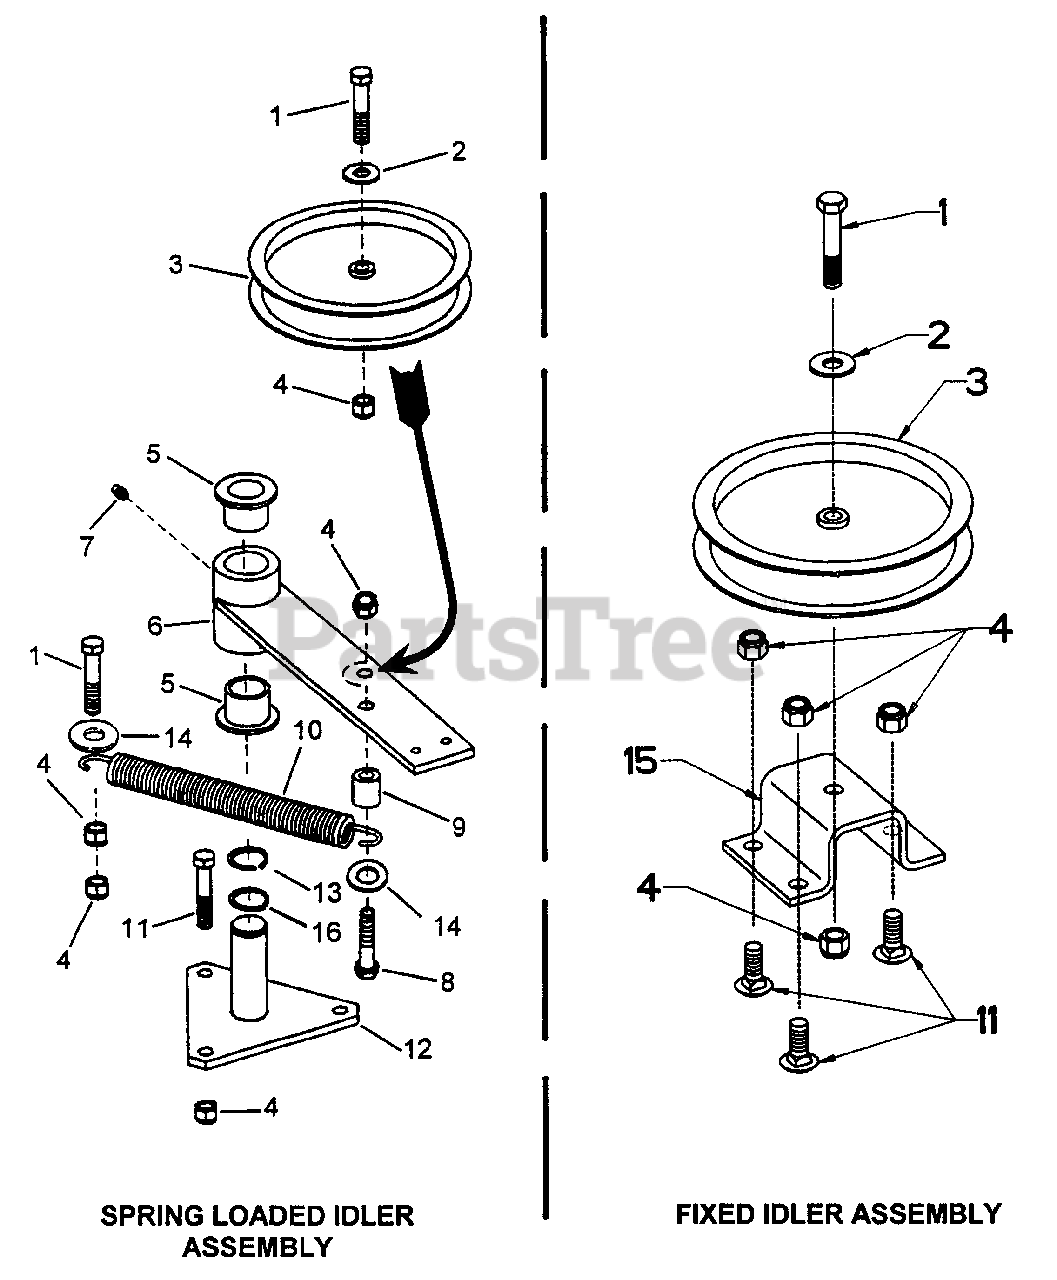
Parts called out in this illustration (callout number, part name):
1	BOLT, 3/8-16 X 2, GD5, CZ
2	WASHER, 3/8" USS
3	PULLEY, Idler 5-1/2" O.D.
4	NUT, 3/8-16 HEX NYLON LOCK
5	BUSHING
6	ARM, Idler (Weldment)
7	FITTING, Lube 1/4-28 Straight
8	SCREW, 3/8-16 x 1-3/4" Hex Head Cap, Grade 5
9	SPACER, .50 I.D. x.75 O.D. x.83
10	SPRING, Extension
11	BOLT, 3/8-16 x 1" Square Neck Carriage, Grade 5
12	PLATE, Tri-Mount (Weldment)
13	E-RING 1"
14	WASHER, .406 x 1.5 x .120 Yellow Zinc
15	STAND, Fixed Idler
16	WASHER, 1.031 x 1.25
